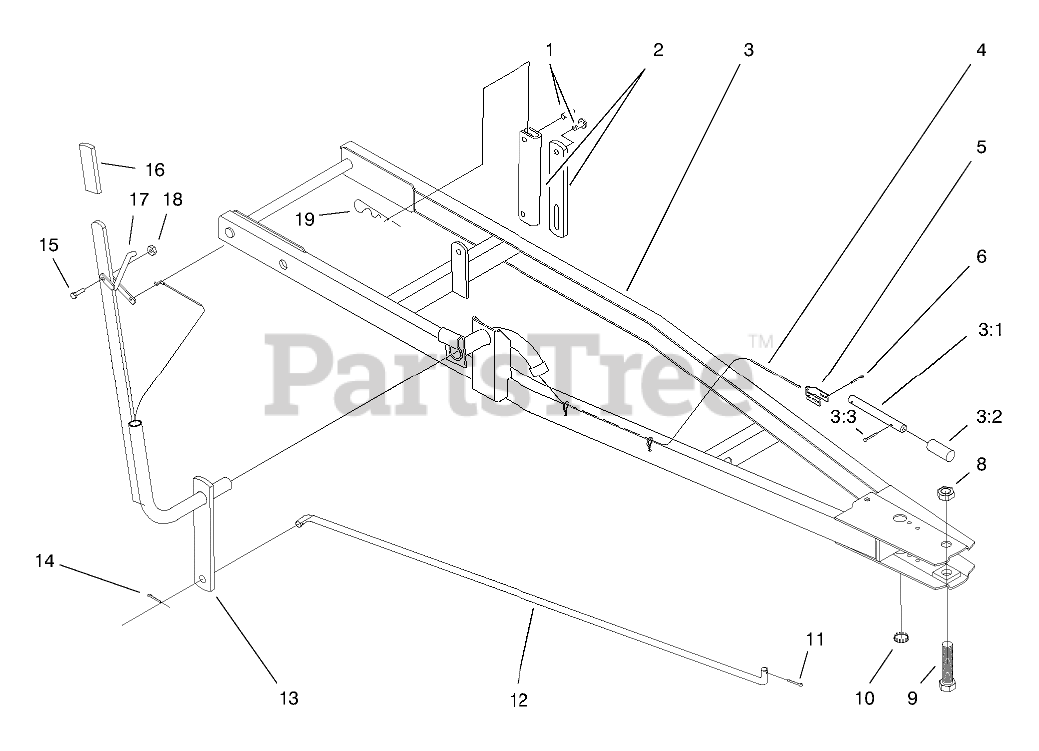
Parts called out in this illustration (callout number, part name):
1	PIN-CLEVIS
1	PIN-WELD
2	LINK - LIFT
3	WA - FRAME PAINT RED
3:1	PIN-INDEX
3:2	SPRING-COMPRESSION
3:3	PIN-COTTER
4	CABLE - INDEXING
5	BRACKET - CABLE END
6	PIN-COTTER
8	NUT-LOCK, NI
9	SCREW-HH
10	PLUG
11	PIN-COTTER
12	ROD - BLADE CONTROL
13	Lever Indexing
14	PIN-HAIR
15	SCREW-HH
16	GRIP
17	LEVER
18	NUT-LOCK
19	PIN-HAIR
